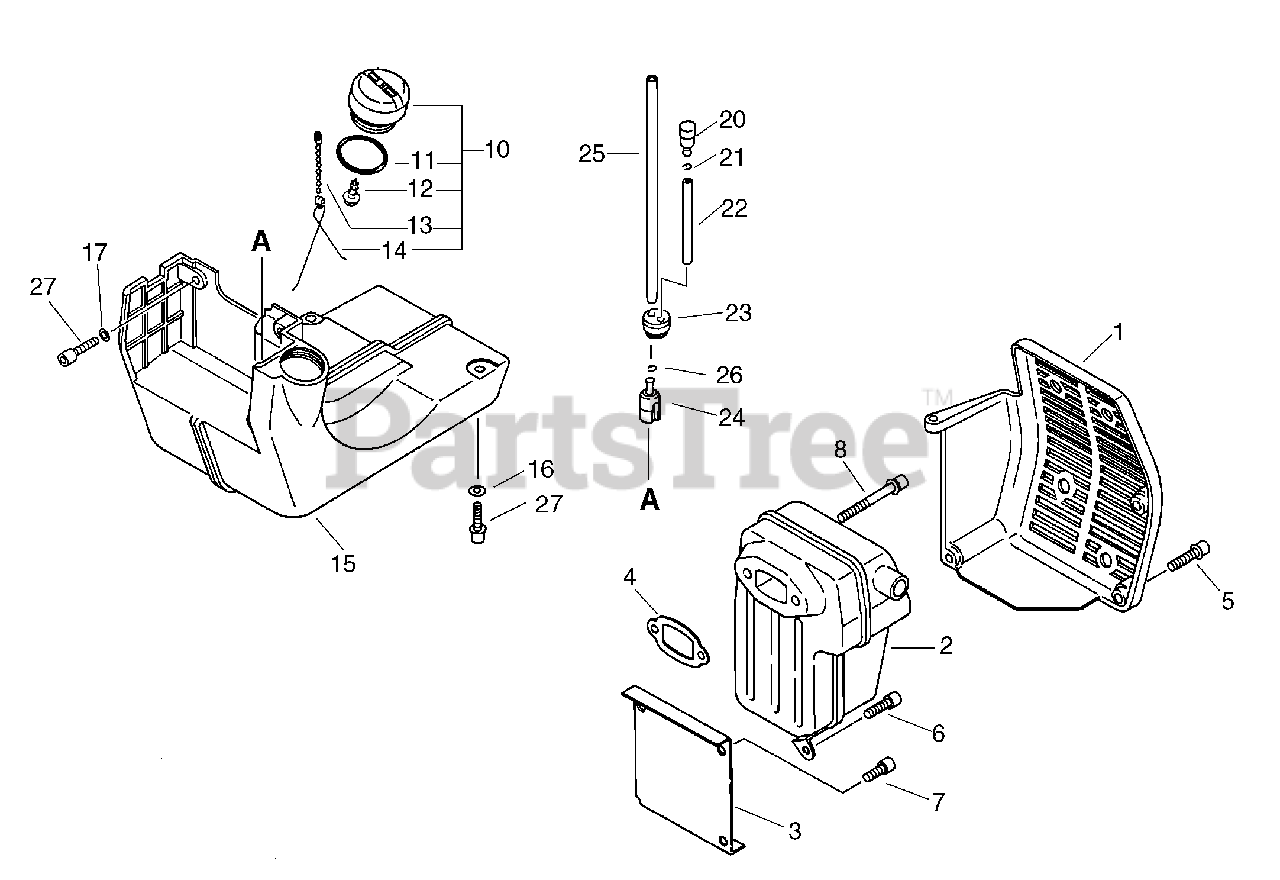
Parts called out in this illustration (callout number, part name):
1	COVER, MUFFLER
2	MUFFLER ASSY
3	INSULATOR, MUFFLER
4	GASKET, EXHAUST
5	SCREW 5×18
6	BOLT 5×16
7	BOLT M5×10
8	BOLT 5×75
10	CAP ASSY, FUEL
11	O-RING 32
12	SCREW, TAPPING 3×8
13	CONNECTOR, CAP
14	RETAINER
15	TANK, FUEL
17	WASHER, FLAT 5.5×10×0.8
20	VENT ASSY
21	CLIP 6 MM
22	PIPE, FUEL
23	GROMMET, FUEL
24	FILTER, FUEL
26	CLIP 6.5 MM
27	SCREW 5×16
